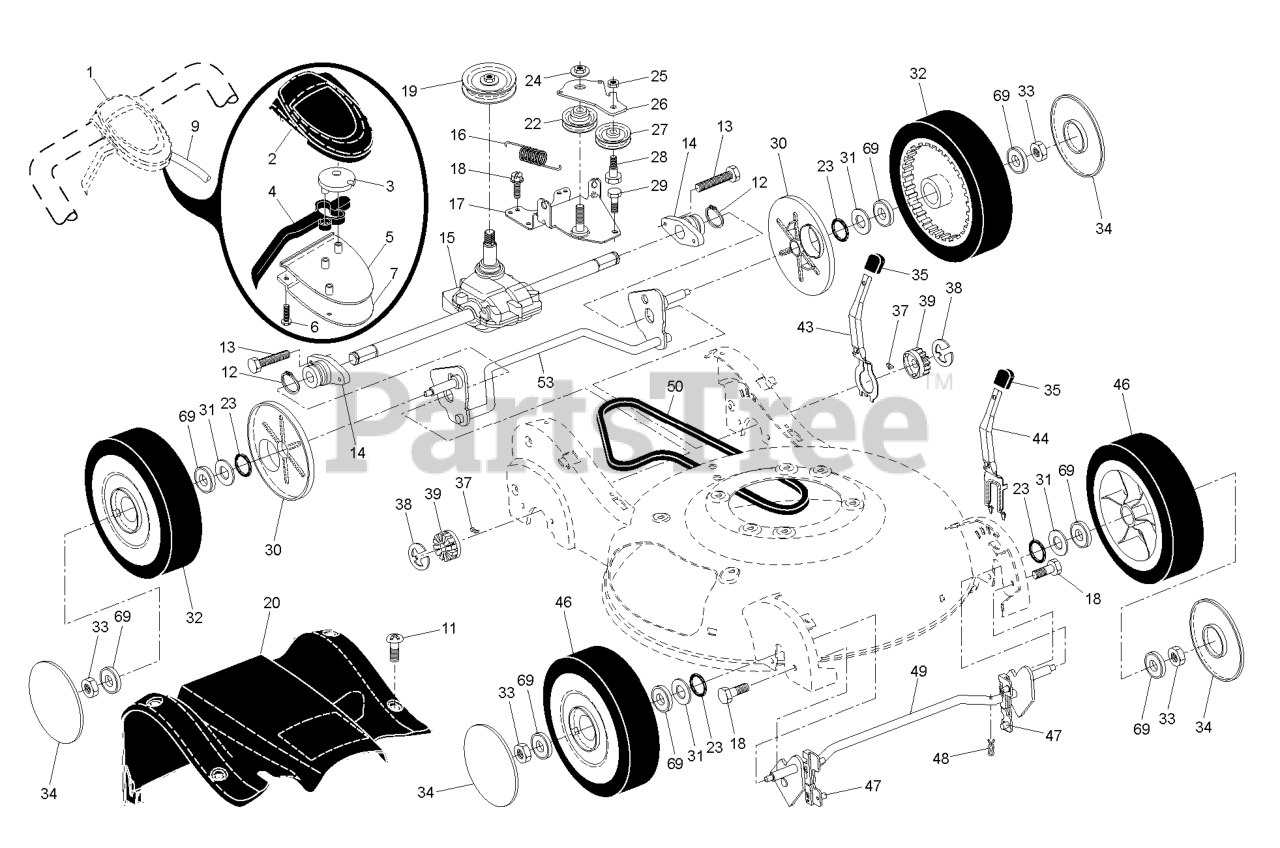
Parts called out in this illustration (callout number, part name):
1	Drive Control Assembly, Complete
2	COVER TOP AUTO WALK CONTROL
3	PULLEY.CAM.DRIVE.CONTROL.HV
4	LEVER
5	COVER BOTTOM AUTO WLK CONTROL
6	SCREW, PHILLIPS HEAD 10 X 5/8
7	BRACKET.DRIVE.CONTROL.MOUNT.BL
9	ASM.CABLE.
12	RETAINING RING (2 2)(3 2)
13	SCREW.1/4-20X21/4.HEX.
14	BEARING / AXLE SUPPORT
15	TRANSMISSION.21.HV.RWGD.AW/EZ
17	BRACKET, GEAR CASE / DRIVE
19	RP PULLEY.DRIVE.EZ
22	PULLEY.IDLER.V-BELT
23	O-RING..070X.487.NEOPRENE
24	NUT.HEX.FLANGE.3/8-16.LOCKNUT
25	NUT.CENTERLOCK.5/16-
26	ARM.IDLER.BZP
27	IDLER PULLEY
28	SHOULDER BOLT
29	SCREW 14-20 X 5/8
30	DUST COVER, WHEEL
31	WASHER.FLAT.1/2
32	WHEEL.9X2.25.LP.TIGER.BLACK
33	NUT.HEX.FLANGE.3/8-16.LO(3 2)
34	HUBCAP.WHEEL.5.SPOKE.SILVER
35	KNOB.SELECTOR.SPRING.BLACK(3 2
37	PAWL, DRIVE
38	E-RING 7/16 RE
39	PINION.14.TEETH.FGD
43	LEVER, SELECTOR, HEIGHT, REAR
44	LEVER, SELECTOR, HEIGHT, FRONT
46	WHEEL.9X2.25.LP.TIGER.BLK
47	BUSHING.FRONT.TORQUE.SHAFT
48	SPRING RETAINER
49	SHAFT FRONT
50	BELT, DRIVE
53	SHAFT.ASM.REAR.TORQUE.HV.BZP
69	BEARING.8".WHEEL
